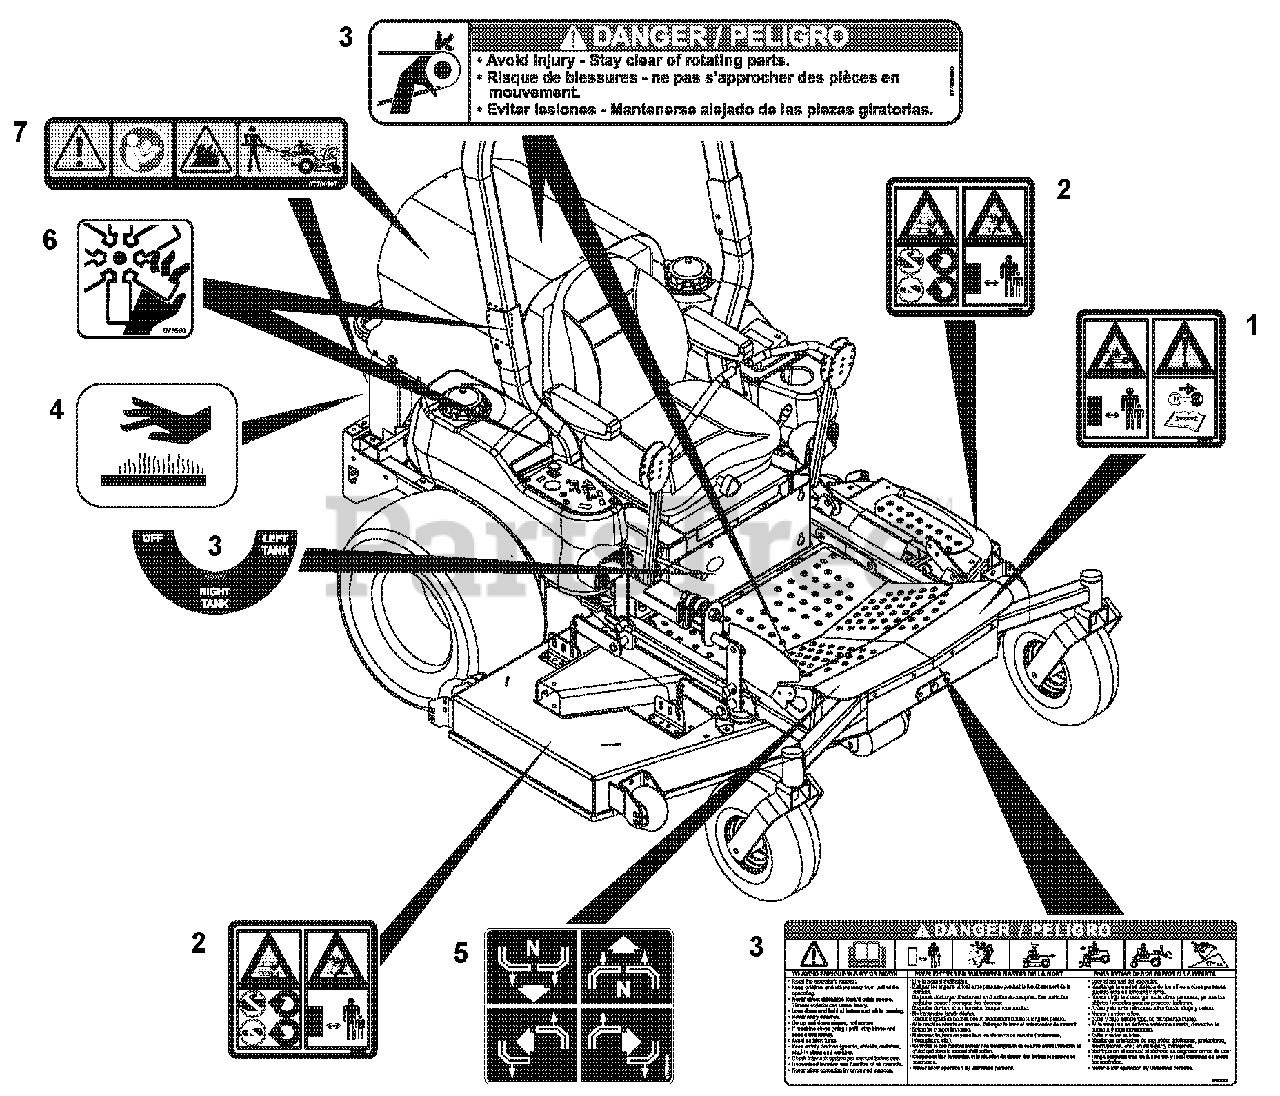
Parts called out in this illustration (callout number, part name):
1	Decal, CE Caution
2	Decal, CE Caution
3	Decal Set, Common Danger/Fuel
4	Decal, Hot Surface
5	Decal, Instructional
6	Decal, Danger Fan
7	Decal, Debris
